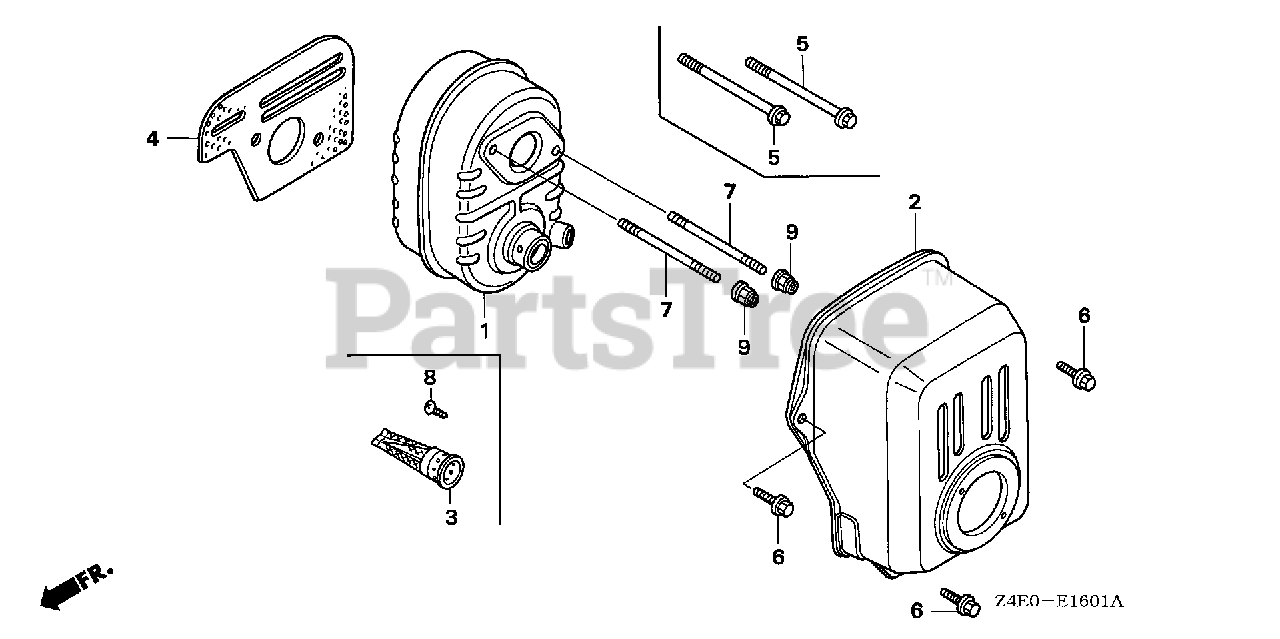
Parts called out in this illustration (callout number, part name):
2	PROTECTOR, MUFFLER
3	ARRESTER, SPARK (TO 1207644)
4	GASKET, MUFFLER
6	BOLT, FLANGE (6X14)
7	BOLT, STUD (6X78) (CT200)
8	SCREW, TAPPING (4X6) (TO INSTALL OPTIONAL SPARK ARRESTER)
9	NUT, SELF-LOCK (6MM)
